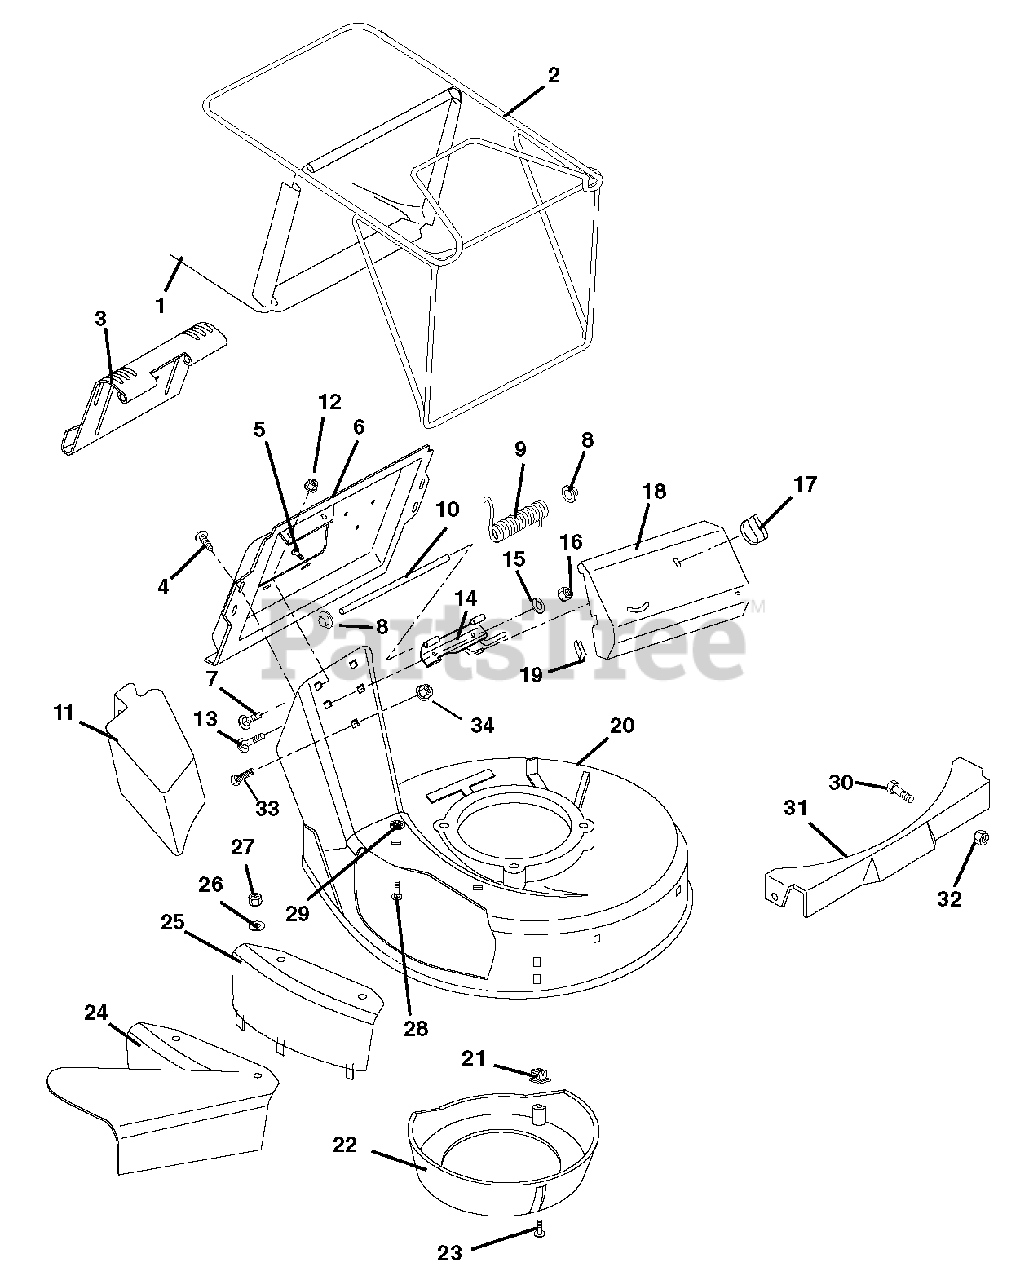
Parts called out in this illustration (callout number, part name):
1	Bag, Consumer Black
2	Frame, Bagger
3	Door, Catcher Plate
4	Screw, Tapping Hex Washer 12-24 x .50
5	Screw, Tapping 10-24 x .38 Pan Head
6	Plate, Catcher
7	Bolt, Round Head Square Neck .25-20 x .50 Grade 5
8	Nut, Push
9	Spring, Torsion .120 x .68 x 3.09
10	Pin, Door
11	Mulch Master Plug
12	Nut, Locking Flange .25-20
13	Bolt, Round Head Square Neck .25-20 x .75 Grade 5
14	Hinge Base Weldment (911196, 197)
15	Washer, Locking .25 x .077
16	Nut, Hex .25-20
17	Nut, Wing (911196, 197)
18	Drive Cover (911196, 197)
19	Trim Bumper
20	Mower Pan Head with Decals (911196, 197)
21	Grommet, Plastic
22	Baffle, Center
23	Screw, Tapping 10-16 x .62 Hex Washer Head
24	Side Discharge Assembly
25	Side Discharge Cover
26	Washer, Flat Steel .406 x .812 x .065
27	Nut, Locking Nylon .312-18
28	Bolt, Round Head Square Neck .31-18 x .75 Grade 2
29	Nut, Push .312
30	Bolt, Round Head Square Neck .31-18 x .50 Grade 5 911170, 192, 193(911196, 171)
31	Front Panel (911196, 171)
32	Nut, Locking-Top-Flange .31-18 (911196, 171)
33	Bolt, Hex .38-16 x .50 Grade 5 (911171)
34	Nut, Locking Flange Nut, .375-16 (911171)
